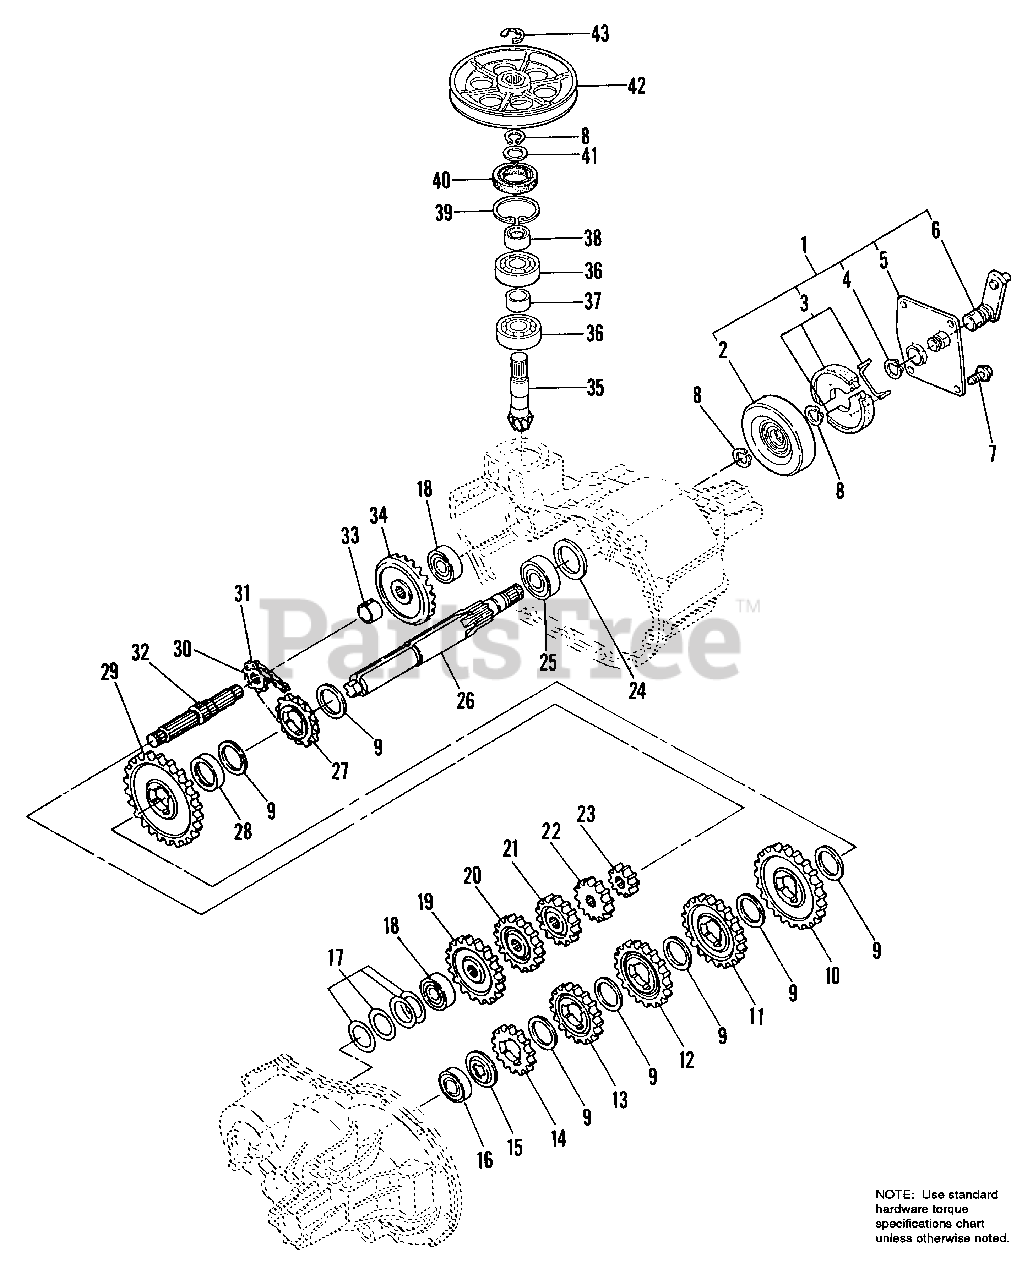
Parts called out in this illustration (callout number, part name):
1	BRAKE ASSY. (Inc. Ref. Nos. 2-6)
2	DRUM, Brake
3	SHOE SET, Brake
4	RING, External Snap
5	COVER, Brake
6	SHAFT, Cam lever
7	BOLT, w/Washer
8	RING, External Snap
10	GEAR, 49 Tooth, Shift
11	GEAR, 38 Tooth, Shift
12	GEAR, 34 Tooth, Shift
13	GEAR, 30 Tooth, Shift
14	GEAR, 24 Tooth, Shift
15	TOOTHED WASHER
19	GEAR, 32 Tooth, Reduction
20	GEAR, 26 Tooth, Reduction
21	GEAR, 23 Tooth, Reduction
22	GEAR, 18 Tooth, Reduction
23	GEAR, 14 Tooth, Reduction
26	SHAFT, Shift
27	SPROCKET, 16 Tooth
28	COLLAR, Neutral
29	GEAR, 62 Tooth, Shift
30	SPROCKET, 9 Tooth
31	CHAIN, Roller
32	SHAFT, Reduction
34	GEAR, 35 Tooth, Ring
35	INPUT GEAR, 9 Tooth, Spiral
39	RING, Internal Snap
42	PULLEY, Input
